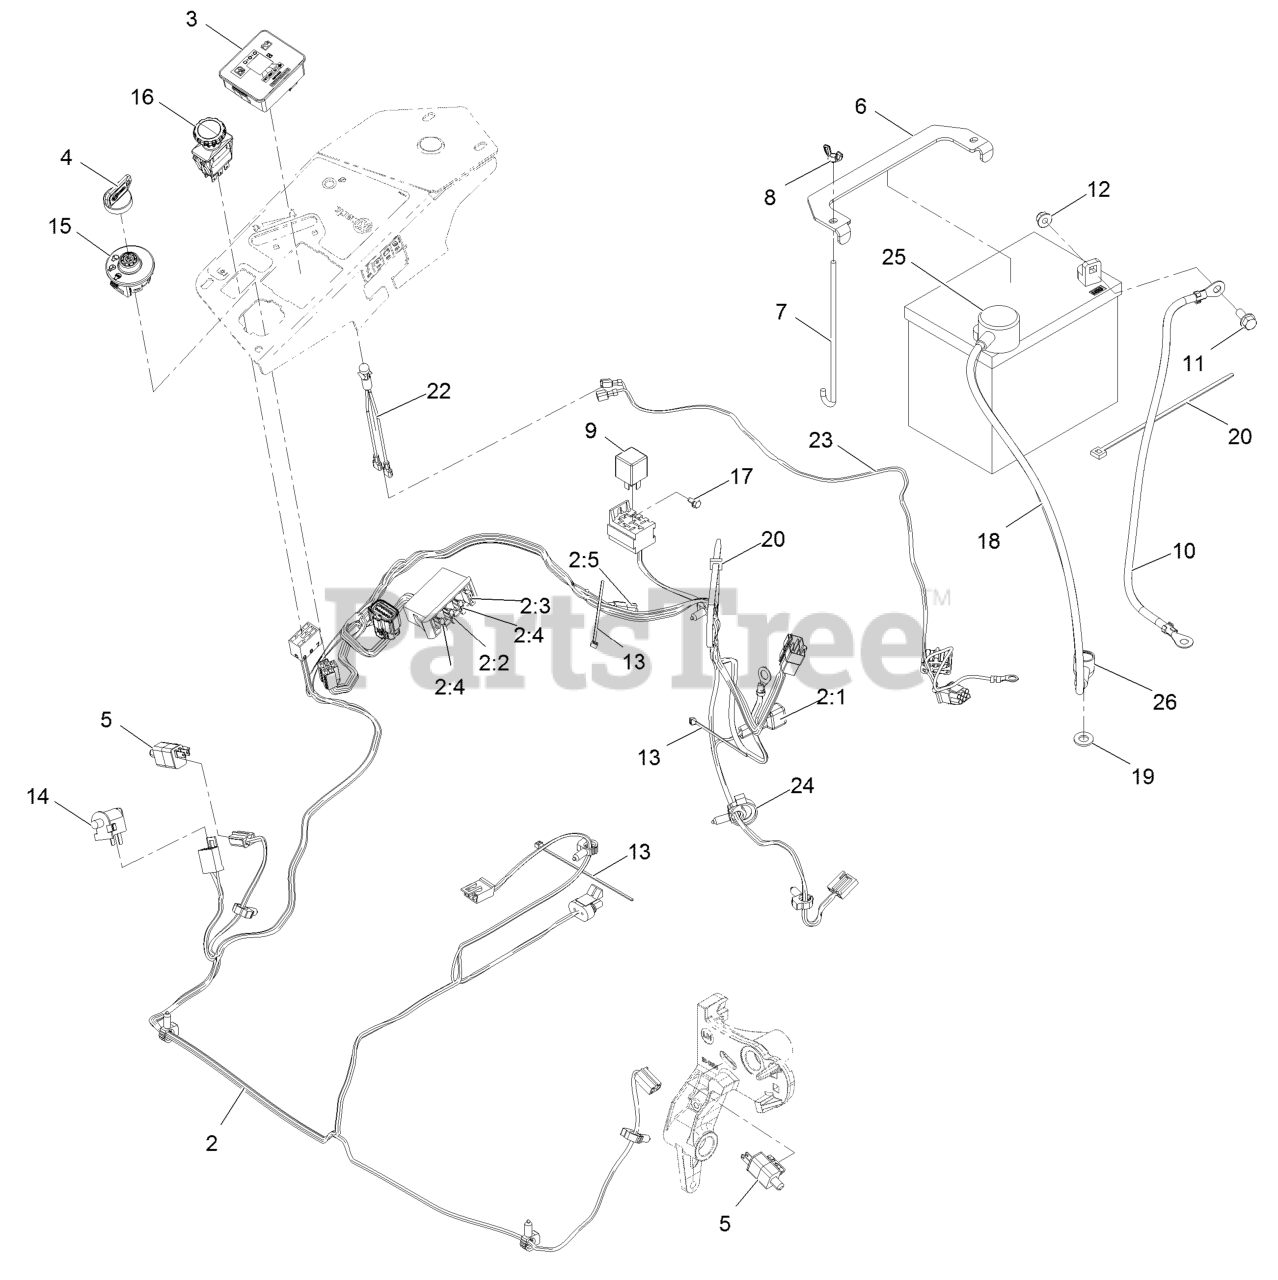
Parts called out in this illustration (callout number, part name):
2	Harness-Wire, Main
2:2	Fuse-Blade, 10 Amp
2:3	Fuse-Blade, 15 Amp
2:4	Fuse-Blade, 25 Amp
2:5	Cap-Plug
3	Fuel/Hour Meter ASM
4	Key-Ignition
4	Key-Exmark Logo
6	Strap-Tie Down, Battery
7	Bolt-Holddown
8	Wingnut-Nyloc 1/4-20
9	Relay-12Vdc 40 Amp
10	Cable-Battery, Negative
11	Screw-HH Flg 5/16-18 X 3/4
12	Nut-Nyloc 5/16-18 Flg
13	Tie-Cable 5 1/2 (Small)
15	Switch-Ignition
16	Switch-PTO, 10 Amp
17	Screw-HWH #10-24 X 3/8
18	Cable-Battery, Positive
19	Washer-3/8 Sae
20	Tie-Cable 7 15/16 (Large)
22	Indicator-Red Led
23	Harness-Light, Indicator
24	Clamp-Hose
25	Insulator-Battery
26	Insulator-Solenoid
